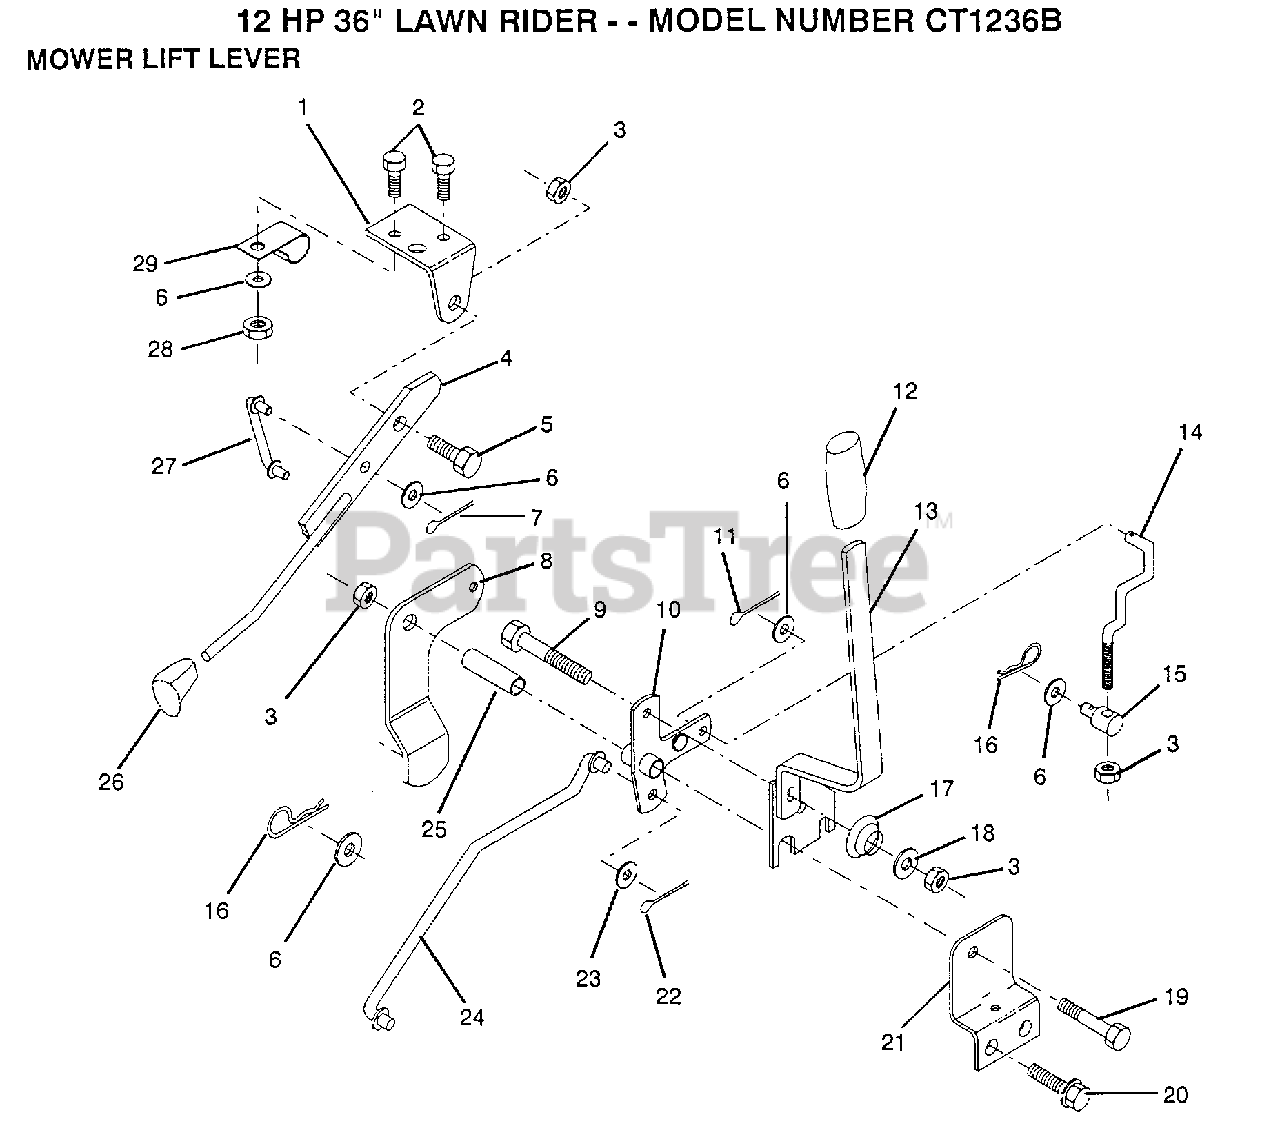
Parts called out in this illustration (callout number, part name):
1	BRKT CLUTCH
2	BOLT
4	CLUTCH LEVER AS
5	"BOLT, SHOULDER LT"
6	WASHER
8	CLUTCH ARM ASS'Y
9	BOLT
10	"BELLCRANK,LIFT"
11	COTTER PIN
12	GRIP HANDLE
13	"HDLE,LIFT T"
14	"LINK,LIFT FRT"
16	SPRING.RETAINER
17	SPRING COMPRESSIO
18	WASHER T
19	BOLT
20	SCREW LT
21	"BRKT,MOWER HGT"
22	PIN COTTER 1/8
24	"ROD,MOWER LIFT "
25	TUBE SPACER
26	KNOB
27	"LINK,MOWER LIFT"
29	"CLIP,INSULATOR"
